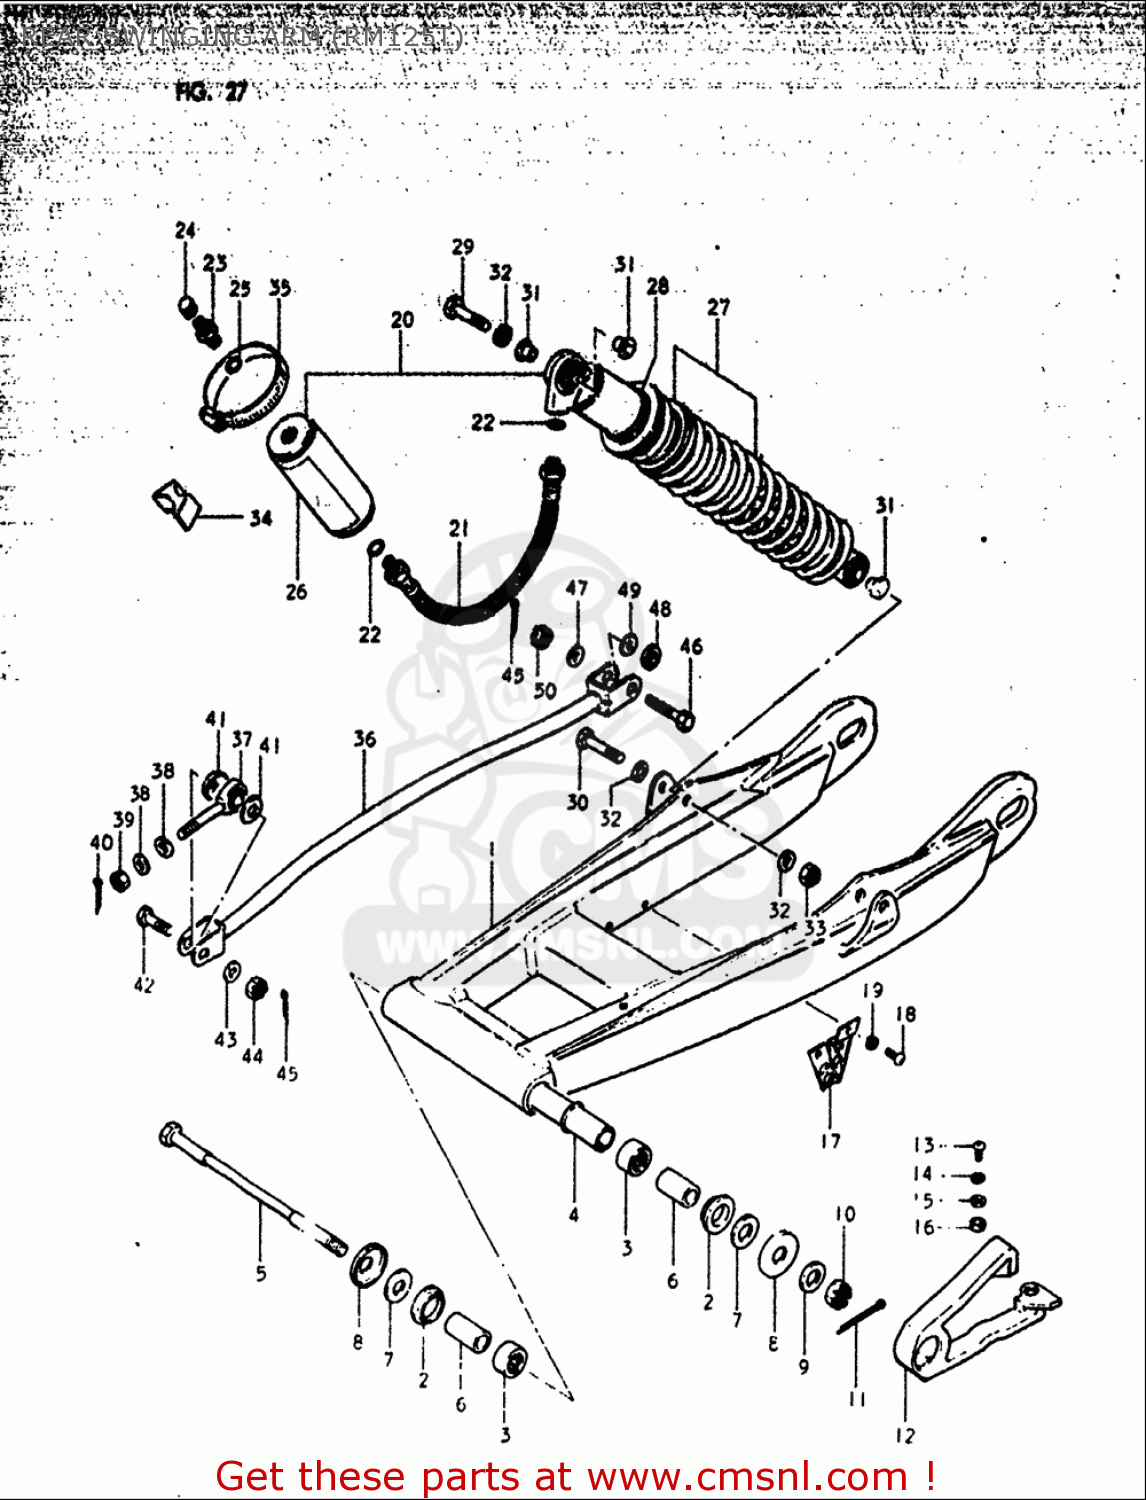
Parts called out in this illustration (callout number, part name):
2	BUSH,RR SWINGINGARM PIVOT
3	BEARING(17X24X20)
4	SPACER
5	SHAFT,RR SWINGINGARM PIVOT
6	SPACER,RR SWGARM PIVOT
7	WASHER
8	COVER,REAR SWING ARM DUST
9	WASHER
10	NUT
11	COTTER PIN
13	SCREW
14	WASHER,LOCK
15	WASHER
16	SPACER(5.5X8X4)
17	GUIDE,CABLE
18	SCREW
19	WASHER,LOCK
23	VALVE
24	CAP,VALVE AIR
25	O RING
30	BOLT(8X46)
31	SPACER,RR SHK ABS INNER
32	WASHER
33	NUT
34	CUSHION,RR SHOCK ABSORBER
38	WASHER
39	NUT
40	PIN
41	DUST SEAL,TORQUE LINK FR BRG
42	BOLT 8X28
43	WASHER
44	NUT
45	PIN
47	WASHER
48	49
49	WASHER (8.5X16X2.6)
50	NUT
